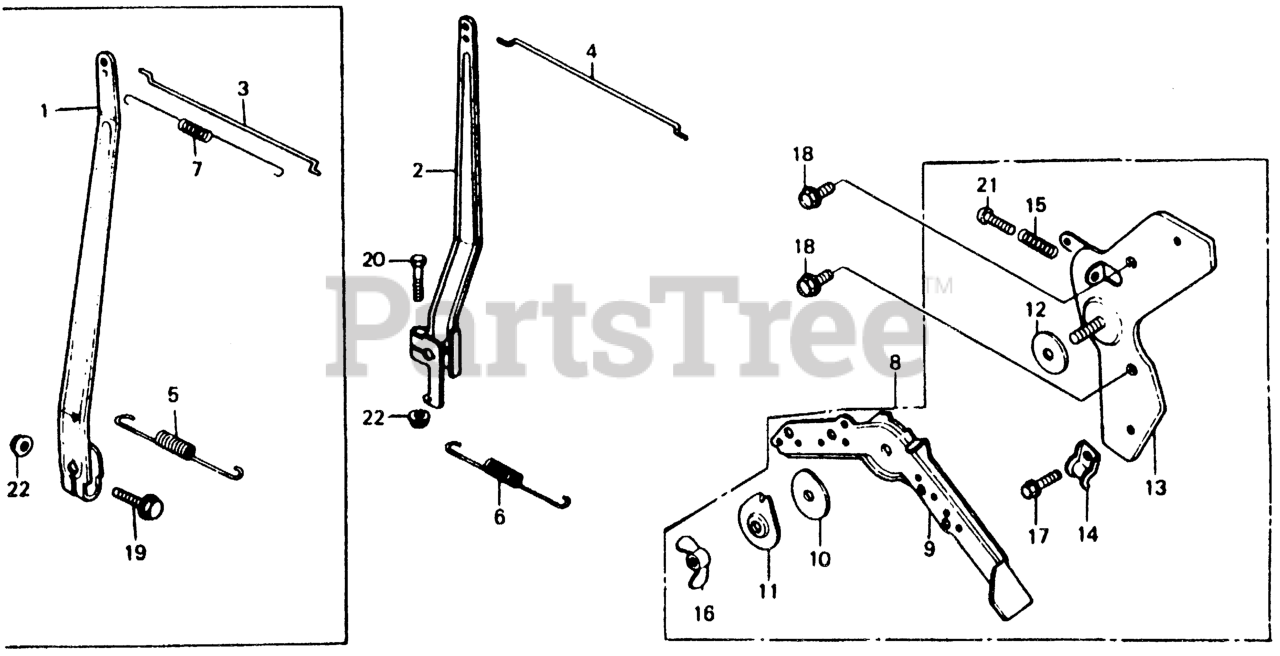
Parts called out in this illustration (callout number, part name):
2	ARM, GOVERNOR
4	ROD, GOVERNOR
6	SPRING, GOVERNOR
8	CONTROL ASSY.
9	LEVER, CONTROL Use from Engine SN 2327377.
10	SPRING, LEVER Use from Engine SN 2327377.
11	WASHER, CONTROL LEVER Use from Engine SN 2327377.
12	SPACER, CONTROL LEVER Use from Engine SN 2327377.
13	BASE, CONTROL LEVER
14	HOLDER, CONTROL CABLE Use from Engine SN 2327377.
15	SPRING, CONTROL ADJUSTING Use from Engine SN 2327377.
16	BOLT, FLANGE (5X10) Use from Engine SN 2327377.
17	BOLT, FLANGE (6X12) (CT200)
18	WINGNUT (6MM) Use from Engine SN 2327377.
20	BOLT, GOVERNOR ARM
21	SCREW, PAN (5X22)
22	NUT, FLANGE (6MM)
